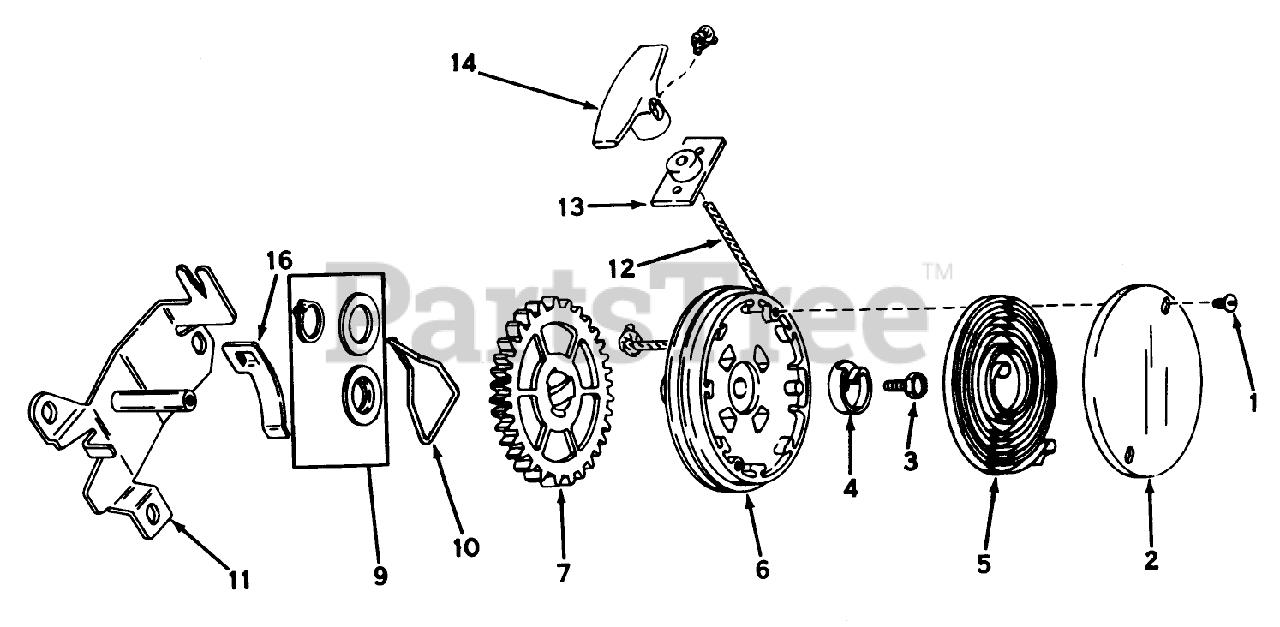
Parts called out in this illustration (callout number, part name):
1	Screw, Cover
2	Cover, Spring
3	Screw, Hex Washer Head
4	Hub Spring
5	Spring, Rewind
6	Pulley Assy. (Incl. No. 9)
9	Kit, Thrust Wash. Snap Rg.
10	Brake
11	Bracket Assy. Mounting
12	Rope, Starter
13	Bracket Assy.
14	Handle-Starter
16	Clip Rope
